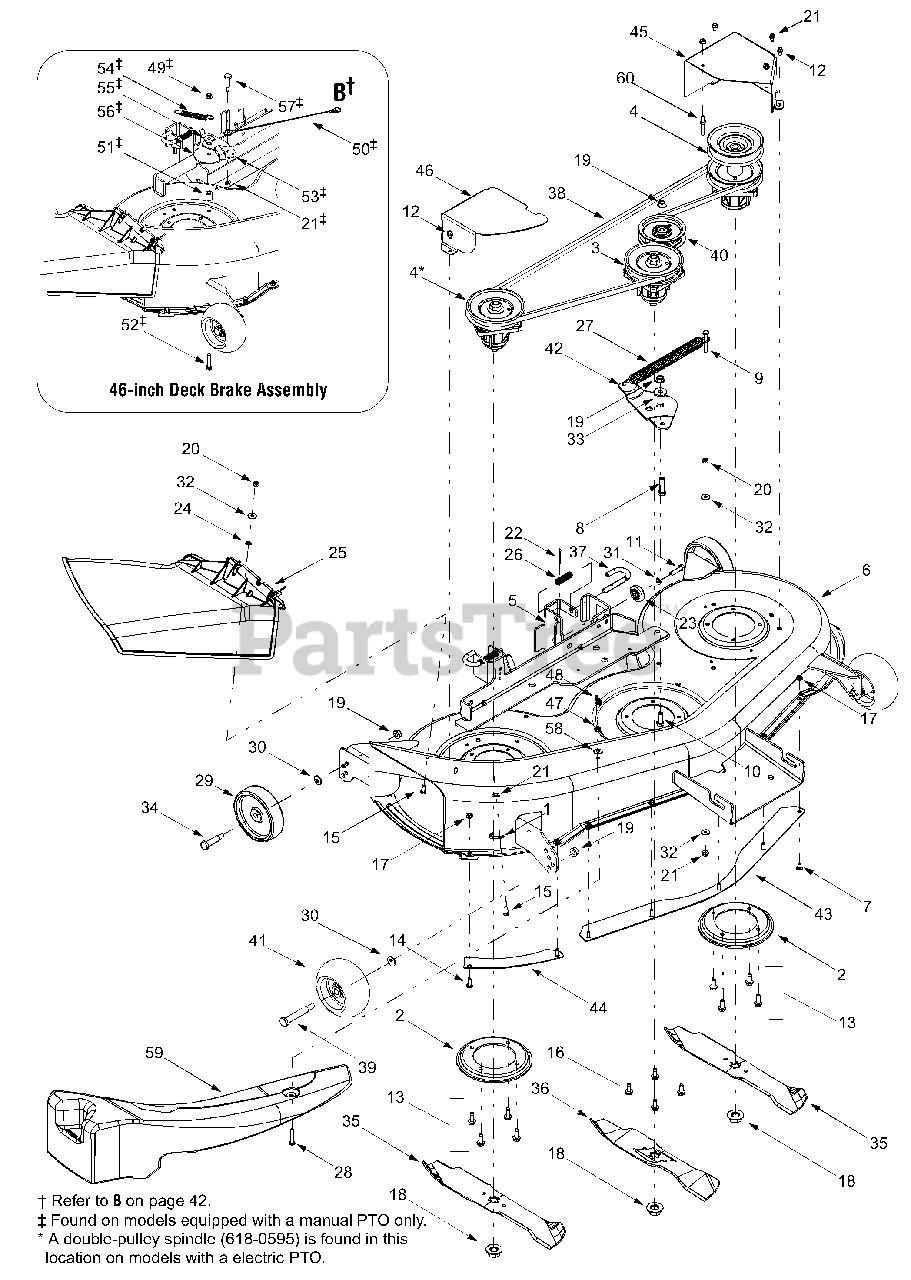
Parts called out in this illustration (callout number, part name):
1	Retainer Hook
4	Double Pulley Spindle Assembly
8	Hex Cap Screw, 3/8-16 x 1.5
9	Hex Cap Screw, 1/4-20 x 2.0
10	Hex Cap Screw, 3/8-16 x 1.0
11	Hex Cap Screw, 5/8-18 x 1.25
12	Self-tapping Screw,1/4-20 x .5
13	Self-tapping Screw,15/16-18 x .875
14	Hex Screw, 1/4-20 x .75
15	Hex Cap Screw, 1/4-20 x .62
16	Self-tapping Screw, 5/16-18 x .75
17	Hex Sems Nut, 1/4-20
18	Hex Flange Nut, 5/8-18
19	Flange Lock Nut, 3/8-16
20	Hex Nut, 1/4-20
21	Hex Flange Lock Nut, 1/4-20
22	Cotter Pin, 1/8 x 1.25
23	Deck Adjustment Gear
24	Push Nut. .25 x .5
25	Side Discharge Chute Assembly
26	Compression Spring, .406 x .531 x 1.75
27	Extension Spring, .91 x 7.3
28	Screw, 1/4-20 x 1.5
29	Deck Wheel, 5 x 1.38
30	Bell Washer, .401 x .87 x .063
31	Lock Washer, 5/16
32	Bell Washer, .265 x .75 x .062
33	Shoulder Spacer, .625 x 1.16
34	Shoulder Screw
35	Three-in-one Blade, Star Center, 16.28"
36	Three-in-one Blade, Star Center, 14.88"
37	Deck Release Pin
38	Deck Belt, Poly
39	Shoulder Screw, 1/2-2.5
40	Idler Pulley, 3.5
41	Deck Wheel, 5.0
45	LH Belt Cover
46	RH Belt Cover
47	Hex Nut, 1/4-20
48	Wing Nut, 1/4-20
49	Hex Nut, 5/16-18
50	Bracket Cable, 12"
51	Spacer, .385 x .625 x .70
52	Hex Cap Screw, 5/16-18 x 1.5
53	Deck Brake Assembly
54	Extension Spring, .5 x 3.97
55	Shoulder Spacer
56	Flat Washer, .320 x 3.0 x .125
57	Shoulder Screw, .374 x 1.16
58	Flat Washer, .28 x .74 x .063
59	Mulch Plug
60	Belt Guard Pin
